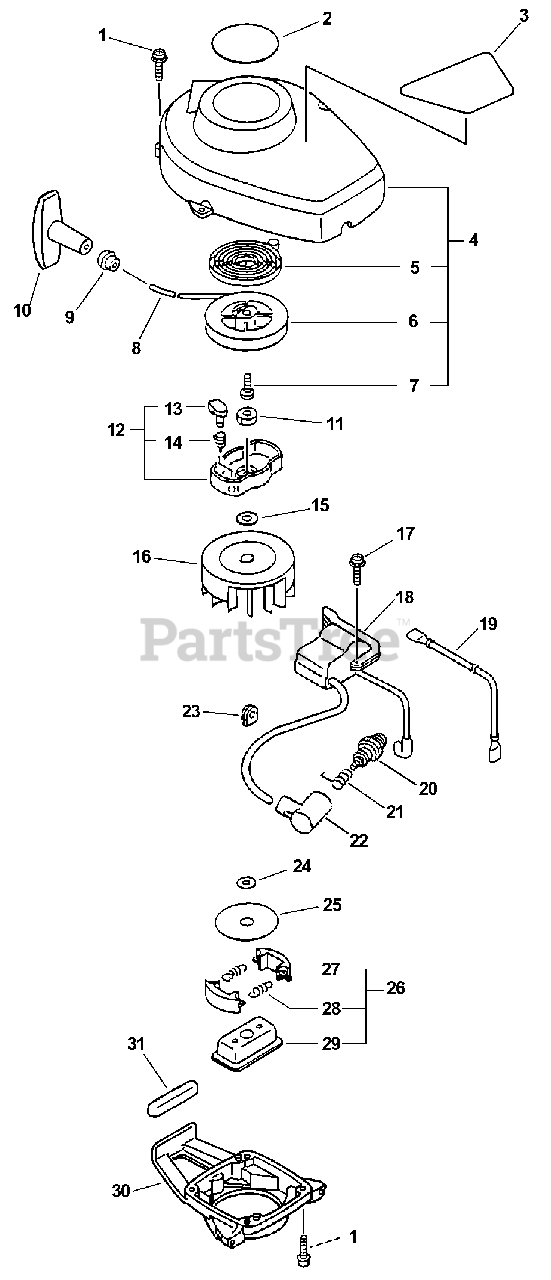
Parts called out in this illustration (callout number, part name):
1	SCREW - 4X16
2	LABEL - MODEL HC-2400
2	LABEL - MODEL HC-2410
3	LABEL - CAUTION
4	STARTER ASSY
5	SPRING, REWIND
6	REEL, ROPE
8	ROPE, STARTER - 3.5X1000
9	GUIDE, ROPE
10	GRIP, STARTER
11	NUT - LEFT HAND
12	STARTER PAWL ASSY
13	PAWL, STARTER - BLACK
14	SPRING, RETURN
15	WASHER - 8
16	FLYWHEEL
17	SCREW - 4X22
18	COIL, IGNITION
19	LEAD - GROUND
20	SPARK PLUG -- BPM-7Y
20	SPARK PLUG -- RCJ-7Y
21	TERMINAL, SPARK PLUG CAP
22	CAP, SPARK PLUG
24	WASHER, CLUTCH
25	PLATE, CLUTCH
26	CLUTCH ASSY
27	SHOE, CLUTCH
28	SPRING, CLUTCH
29	HUB, CLUTCH
30	CASE, CLUTCH
31	CUSHION, FUEL TANK
